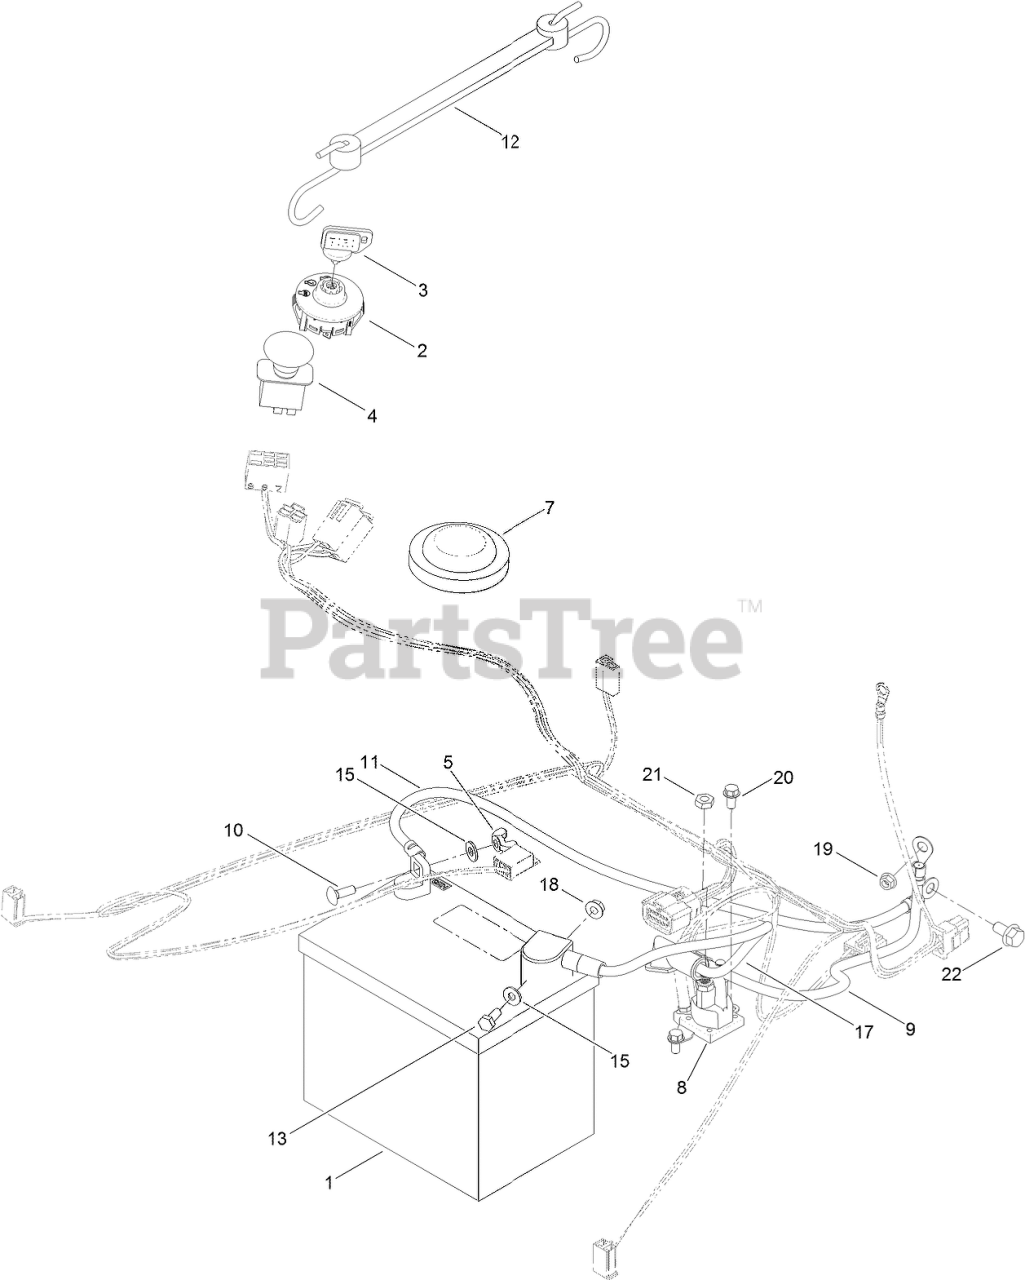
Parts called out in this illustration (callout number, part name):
1	BATTERY
2	SWITCH-IGNITION
3	KEY-IGNITION
4	SWITCH-PTO, ON-ON-(ON)
5	NUT-WING
7	SWITCH-SEAT
8	SOLENOID
9	CABLE-BATTERY, POSITIVE
10	BOLT-CARR
11	CABLE-BATTERY, BLACK
12	HOLDDOWN-BATTERY
13	SCREW-HH
15	WASHER-FLAT
17	CABLE-BATTERY, RED
18	NUT-HF
19	NUT-HF
20	SCREW-HWH
21	NUT-JAM
22	SCREW-HHF
